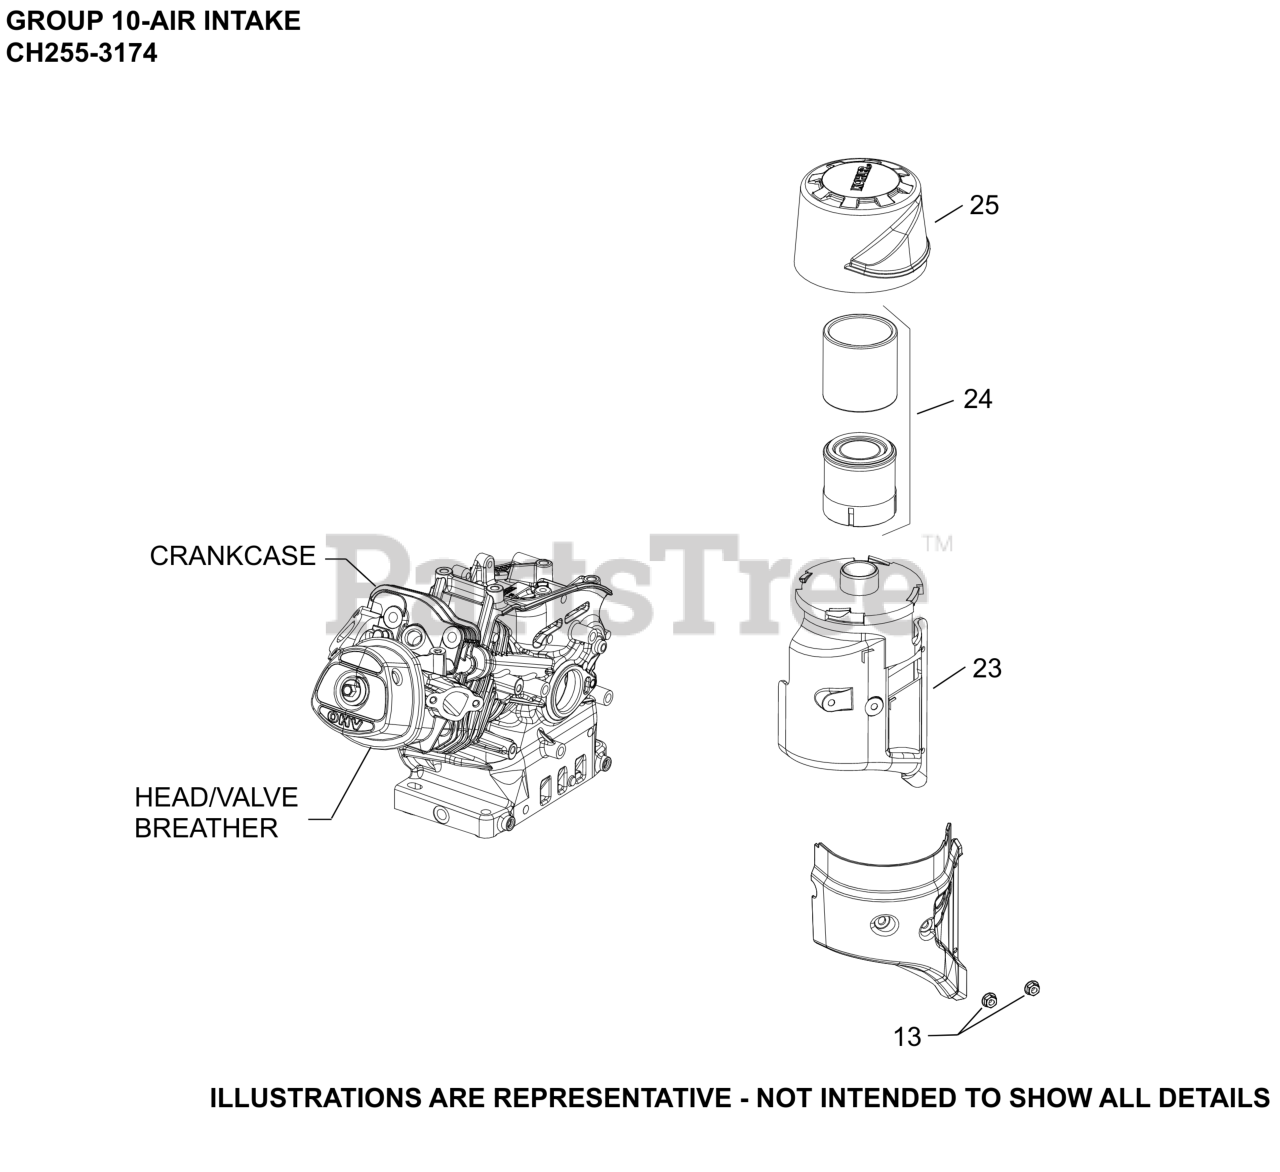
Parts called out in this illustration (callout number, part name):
13	NUT, HEX FLANGE LOCK (M6)
23	BASE, AIR CLEANER ASSEMBLY
24	ELEMENT, FILTER ASSEMBLY
25	COVER, AIR CLEANER ASSEMBLY
